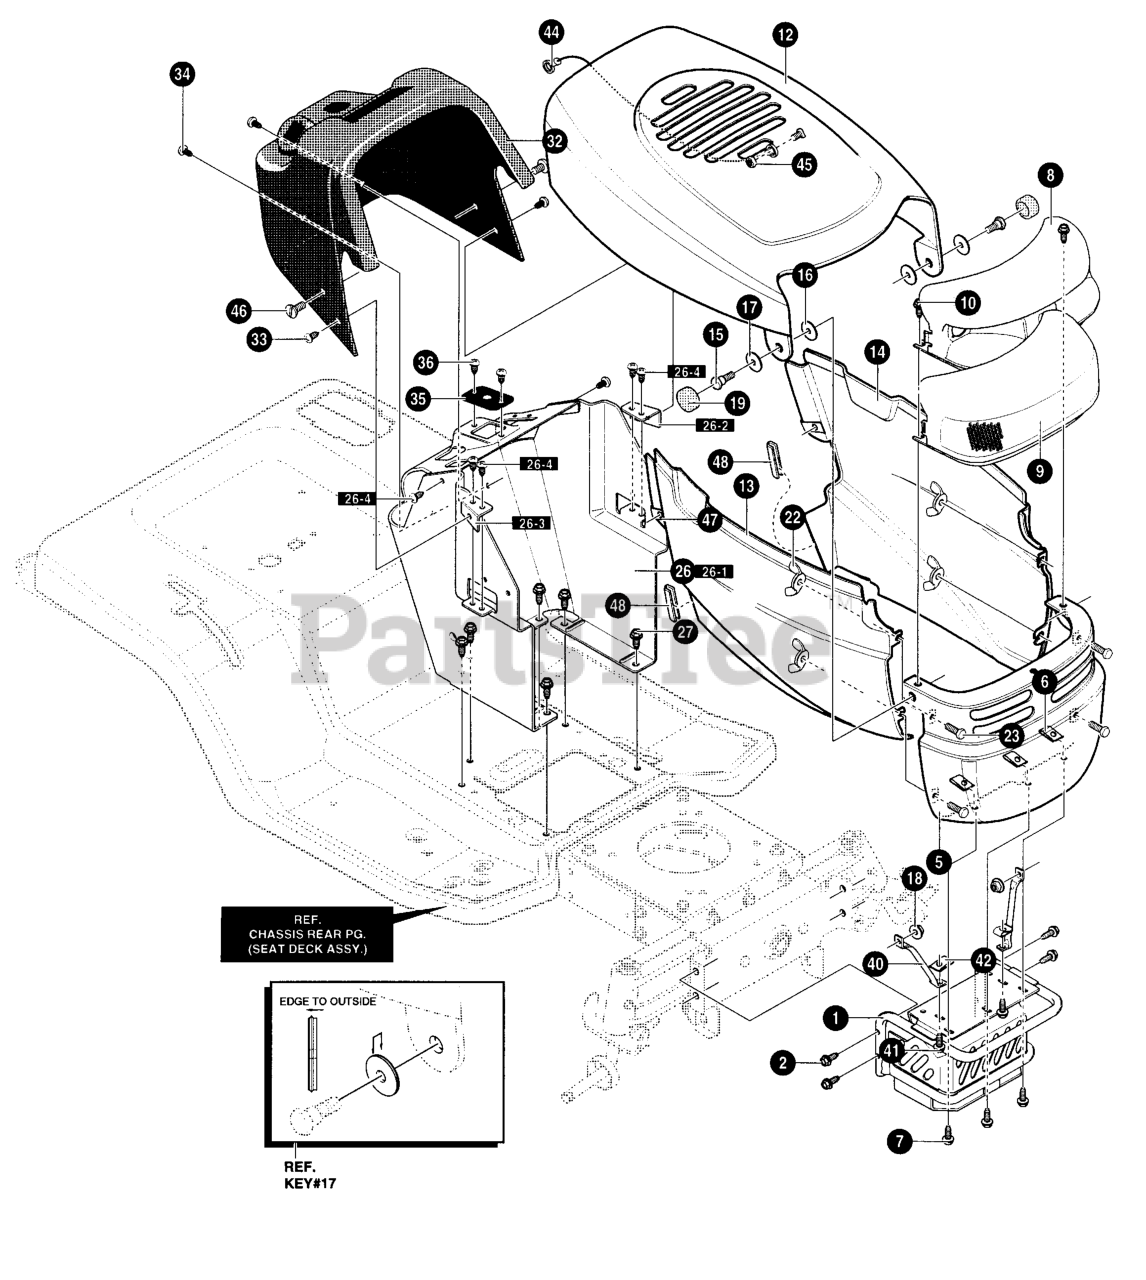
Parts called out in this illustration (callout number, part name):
1	BUMP/GRIL MNT
2	SCREW 5/16-18X1.38
6	NUT, "J" TINNERMAN
7	SCREW 1/4-20X.63
8	REFLECTOR
10	SCREW, 1/4-14X.50
12	ASSEMBLY, HOOD
13	PANEL, SIDE RH
14	PANEL, SIDE LH
16	WASHER, PLASTIC
17	PIVOT BASE
18	NUT, 3/8-16
19	CAP, PIVOT
22	NUT, WING 1/4-20
23	SCREW 1/4-20X1.25
26	CONSOLE ASSY
26-1	CONSOLE, DASH
26-2	BRACKET, LH
26-3	BRACKET, RH
26-4	SCREW, 10-24X.5
27	SCREW 5/16-18
33	SCREW 10-24X.5
34	SCREW 10-24X.5
35	STEERING BEARING
36	SCREW, 1/4-14X.5
40	STRUT, GRILLE
41	SCREW 1/4-20X.63
42	SPEED NUT
44	LANYARD, HOOD
45	NUT, 1/4-20
46	SCREW 1/4-20X.63
47	NUT, "J" TINNERMAN
48	TRIM
